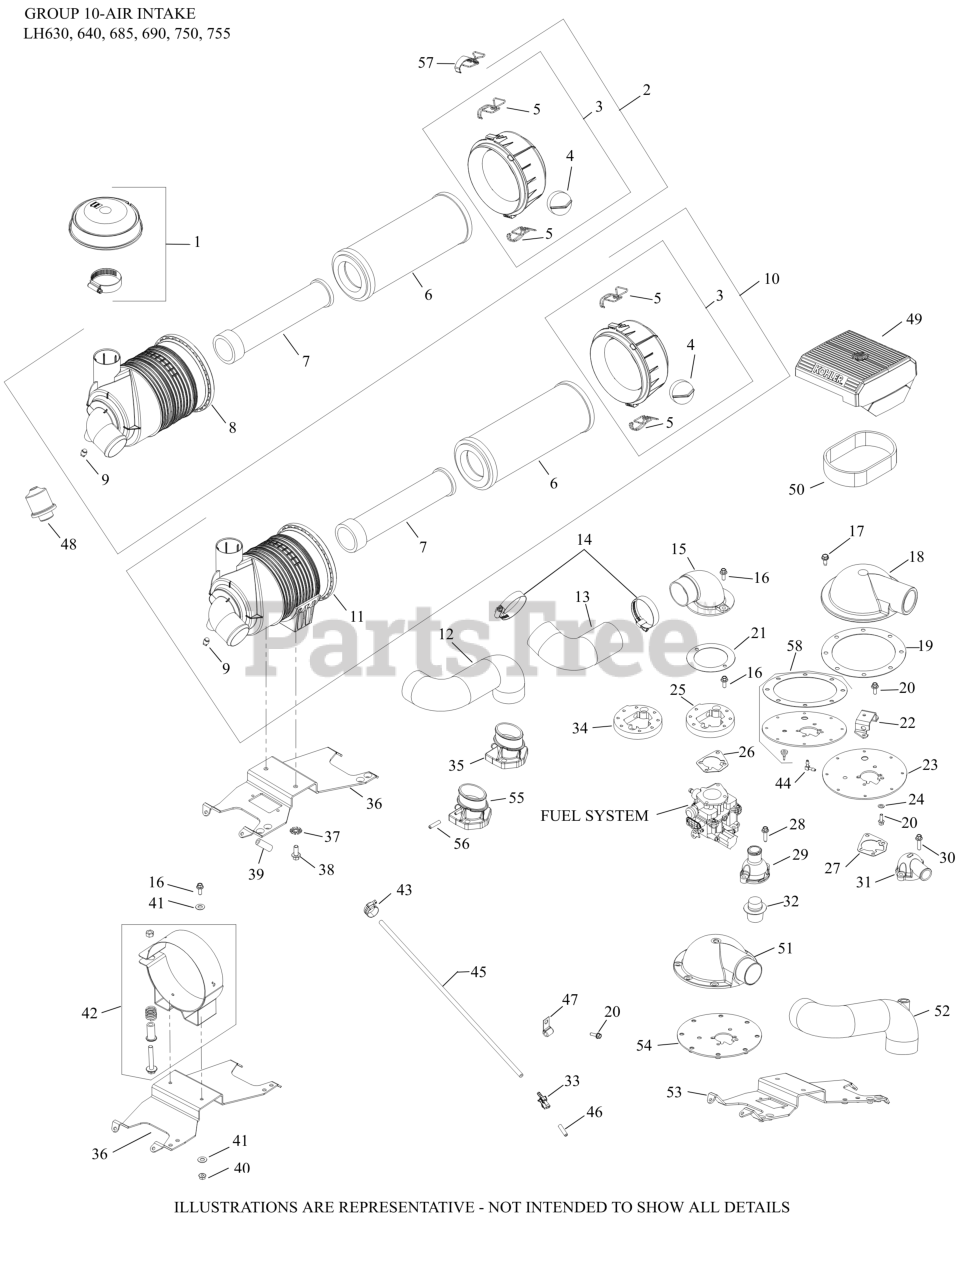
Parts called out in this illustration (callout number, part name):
1	HOOD, AIR CLEANER (5.25)-USE 25 324 04-S
3	COVER ASSEMBLY, AIR CLEANER
4	VALVE, DUST EJECTOR
5	CLIP - USE 62 154 07-S
6	ELEMENT, AIR FILTER - PRIMARY
7	ELEMENT, AIR FILTER - SAFETY
9	PLUG, PIPE
10	AIR CLEANER ASSY
11	HOUSING, HEAVY DUTY A/C
13	HOSE, AIR CLEANER
14	CLAMP, HOSE-USE 25 237 21-S
14	CLAMP, HOSE
15	ADAPTER, REMOTE AIR CLEANER
16	SCREW, FLG M6X1.0X16
17	SCREW,FLG THD FRM M6X1.0X16-(#25086397S)
21	GASKET, ADAPTER
25	ADAPTER ASSY-USE 24 029 97-S
26	GASKET, AIR CLEANER BASE
28	SCREW, FLG M6X1.0X25
29	HOUSING, THERMOSTAT
32	KIT, THERMOSTAT (190 F degree)
36	AIR CLEANER BRACKET
37	Washer, Int Ext Tooth
38	SCREW, FLG M8X1.25X20
57	CLIP ASSEMBLY
